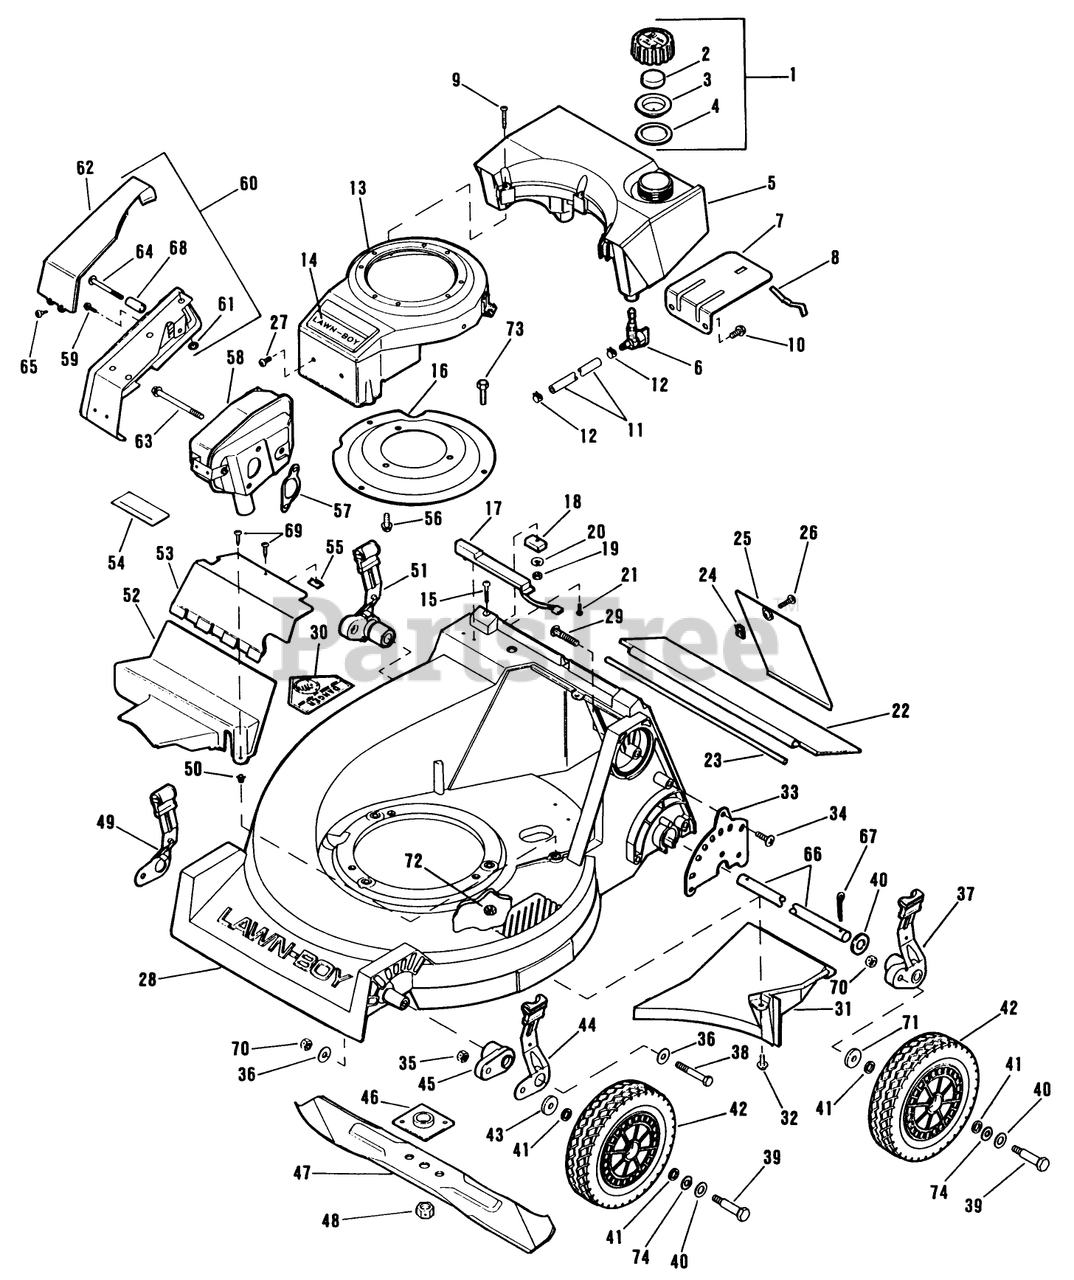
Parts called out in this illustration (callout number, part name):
1	CAP AY - F/OIL SM
2	BAFFLE - FOAM SM
4	GASKET-FUELCAP SM
6	DISC/LB SER.BUL.#6
7	DISC. LB SER.BUL.#6
8	SPRING
9	DISC.LB SER.BUL.#6
11	GAS LINE SM
12	HOSE CLAMP SM
14	APPLIQUE SM
17	SWITCH AY DELTA
24	SPEED NUT LARSON
25	DOOR-ACCESS ELECT.
26	SCREW-CROSS RECESS
31	CHUTE BAFFLE NYL
33	PLATE HGT CMS
34	SCREW-BHTF
35	NUT-JAM, LOCKING
36	WASHER-PLAIN
37	HT. ADJ. ARM AY-L
39	BOLT WHEEL QUAL
40	SPACER
41	WASHER
42	WHEEL&TIRE 8" TRI
43	WASHER
44	KNOB & SPRING CMS
45	ARM HGT ADJ *BLACK
46	PLATE AND COLLAR ASM
48	NUT-BLADE
49	KNOB & SPRING CMS
50	NUT-CLIP
51	HT. ADJ. ARM AY-R
55	NUT-SPEED
57	GASKET - EXH SM
59	SCREW S
60	MUFFLER GUARD AY
61	NUT-PUSH
62	COVER MUFFLER CP
63	SCREW-SEMS
64	SCREW SM
65	SCREW SM
66	ROD HGT ADJ R GLM
68	SPACER S
69	SCREW S
70	LOCKNUT
71	WASHER WROUGHT
72	NUT-LOCK F
73	SCREW-HH
74	WASHER
